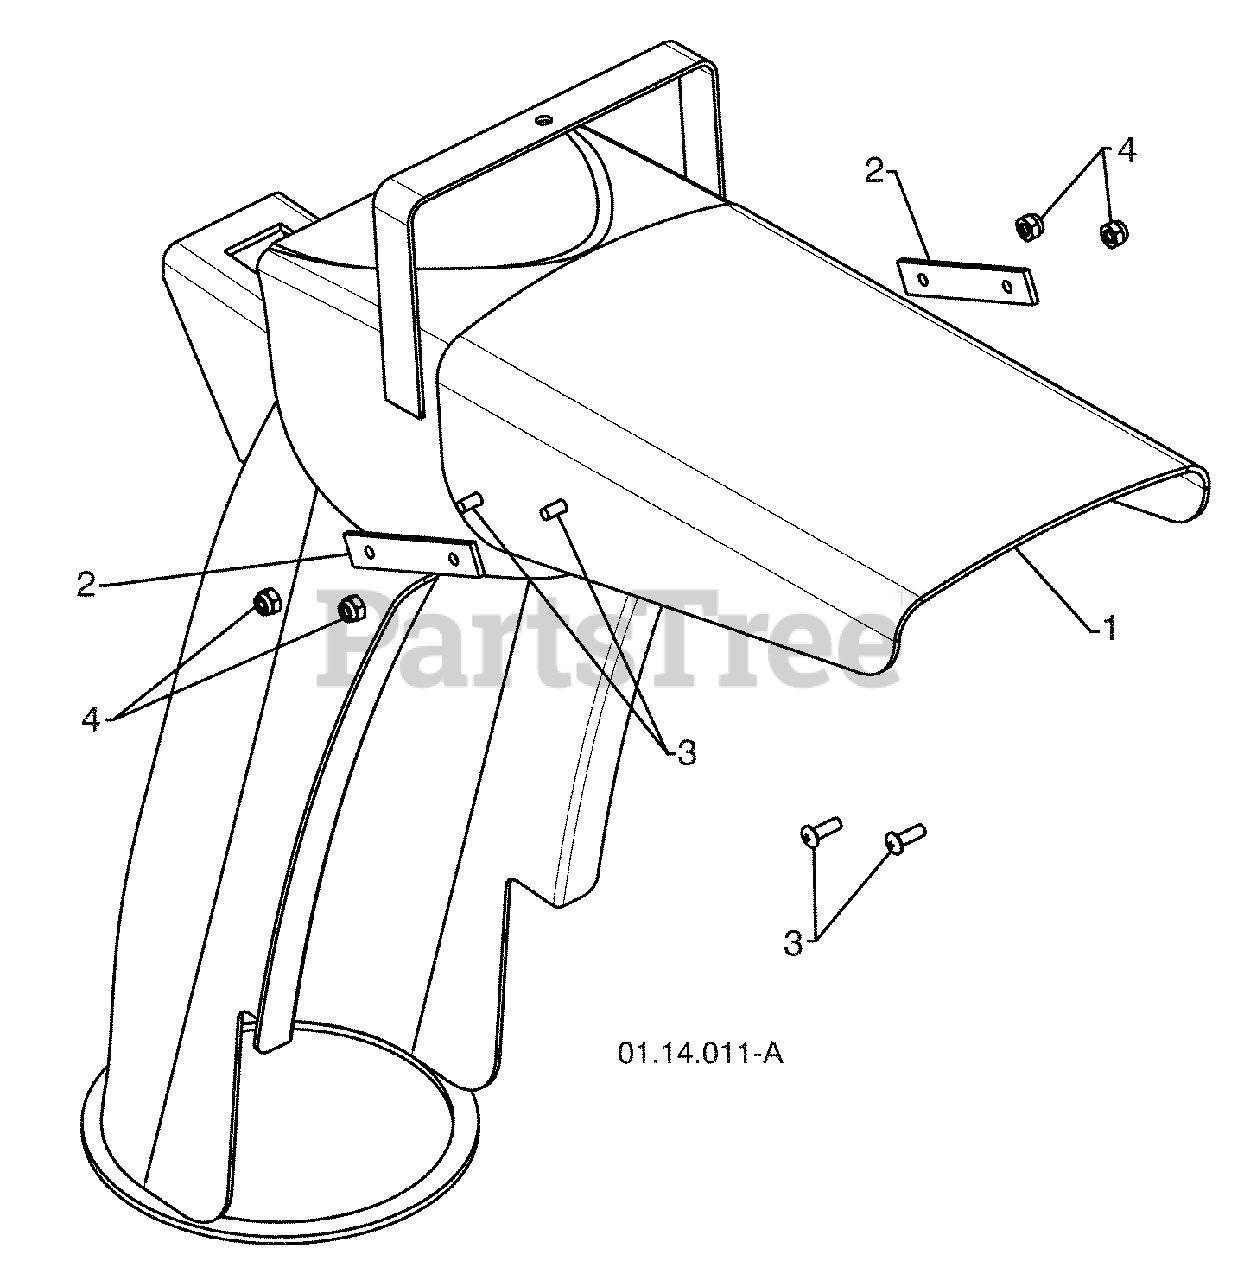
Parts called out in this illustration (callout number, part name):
1	SHIELD DEFLECTOR
2	STRAP
3	SCREW 8-32 X .50
